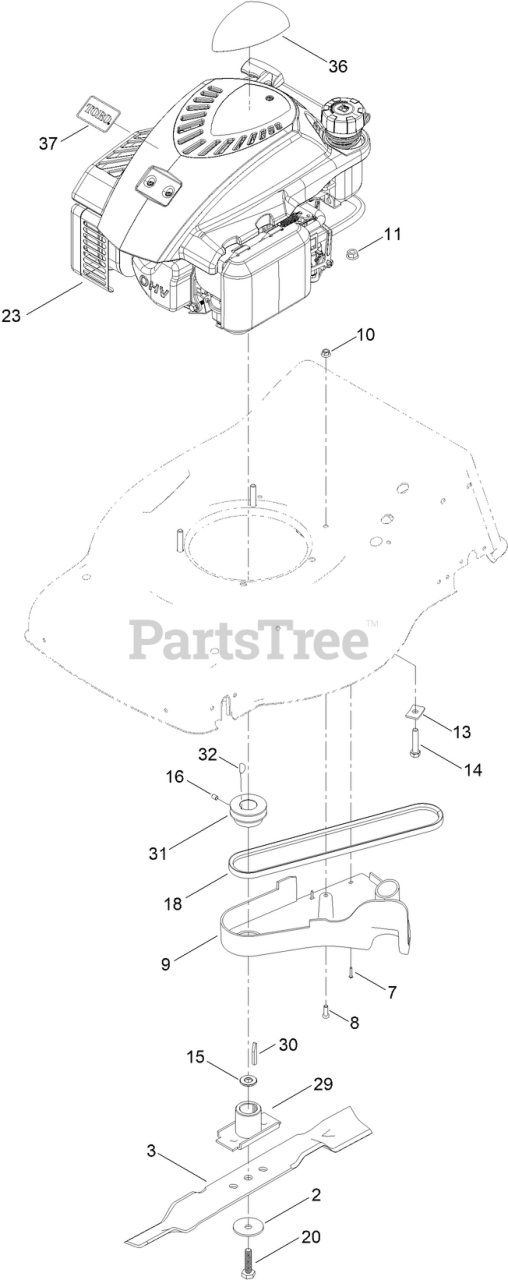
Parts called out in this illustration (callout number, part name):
2	WASHER-DISHED
3	BLADE-MULCH
7	SCREW-SELF DRIVING
8	SCREW-TOOTH
9	COVER-PULLEY, BELT
10	NUT-LOCK, FLANGE
11	NUT-LOCK, FLANGE
13	WASHER-SQUARE
14	BOLT-BLADE
15	SHEATH-BLADE
16	SCREW-GRUB
18	BELT-TRIANGLE
20	BOLT-BLADE
23	ENGINE-1P65FC, RECOIL
29	SUPPORT-BLADE
30	KEY-FLAT
31	PULLEY-DRIVE
32	KEY-WOODRUFF
36	DECAL - ENGINE
